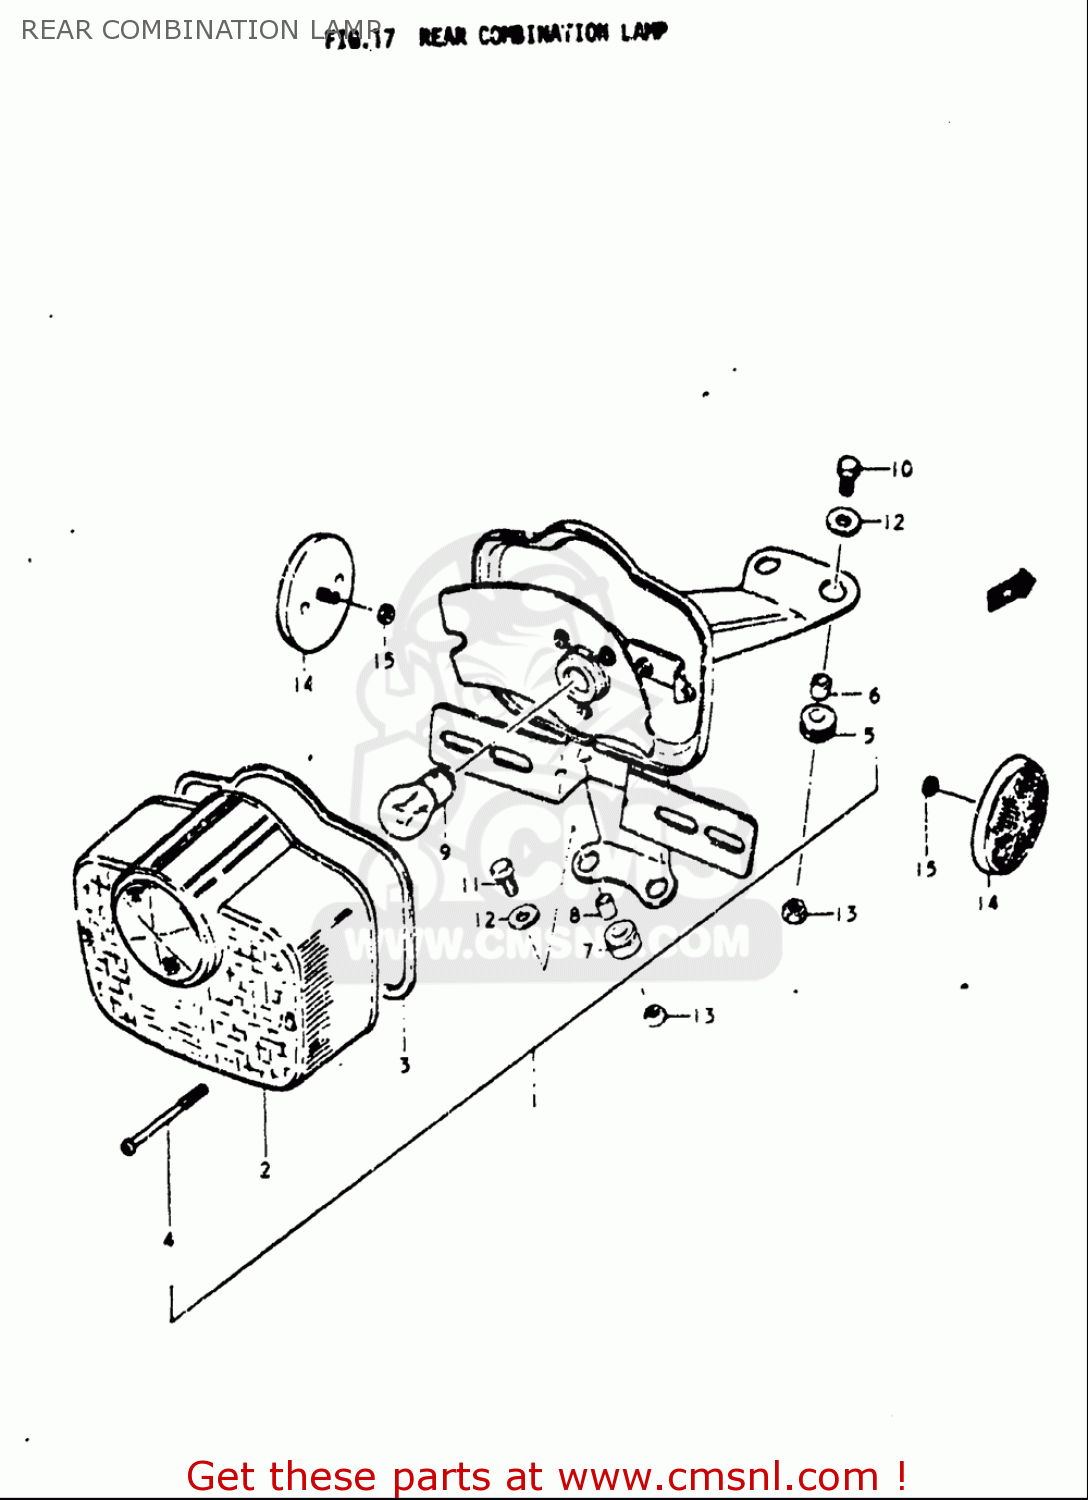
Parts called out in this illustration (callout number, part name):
2	LENS
3	GASKET (NAS)
5	CUSHION
6	SPACER
7	CUSHION
8	SPACER
9	BULB(6V32/3CP,STANLEY)
10	BOLT
11	BOLT
12	WASHER(6.5X20X1.2)
13	NUT
15	NUT
